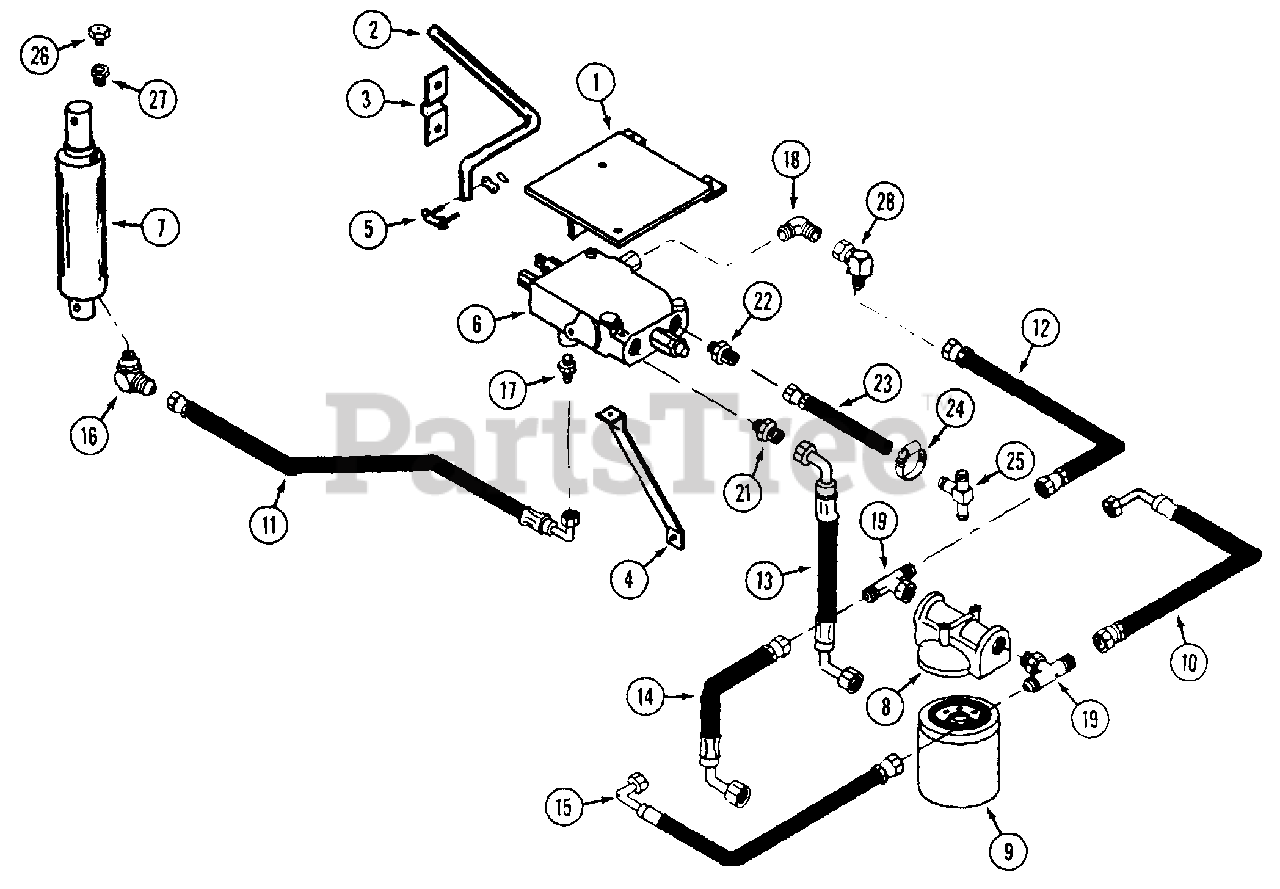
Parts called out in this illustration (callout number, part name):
1	MOUNT - valve
2	LEVER - actuator
4	SUPPORT - valve
5	CONNECTING LINK - #50
6	VALVE - lift
7	CYLINDER - lift
8	HOUSING - oil filter
9	ELEMENT - oil filter
10	HOSE - 3/8" ID x 26" long
11	HOSE - 3/8" ID x 31" long
12	HOSE - 3/8" ID x 20" long
13	HOSE - 3/8" ID x 13" long
14	HOSE - 3/8" ID x 11.5" long
15	HOSE - 3/8" ID x 21" long
16	FITTING - 90° male tube adp.
17	FITTING - straight
18	FITTING - tee
21	FITTING - straight
22	FITTING - straight
23	HOSE - 1/2"
24	CLAMP - hose
25	FITTING - tee
26	BREATHER
27	FITTING - adaptor
28	FITTING - 90°
